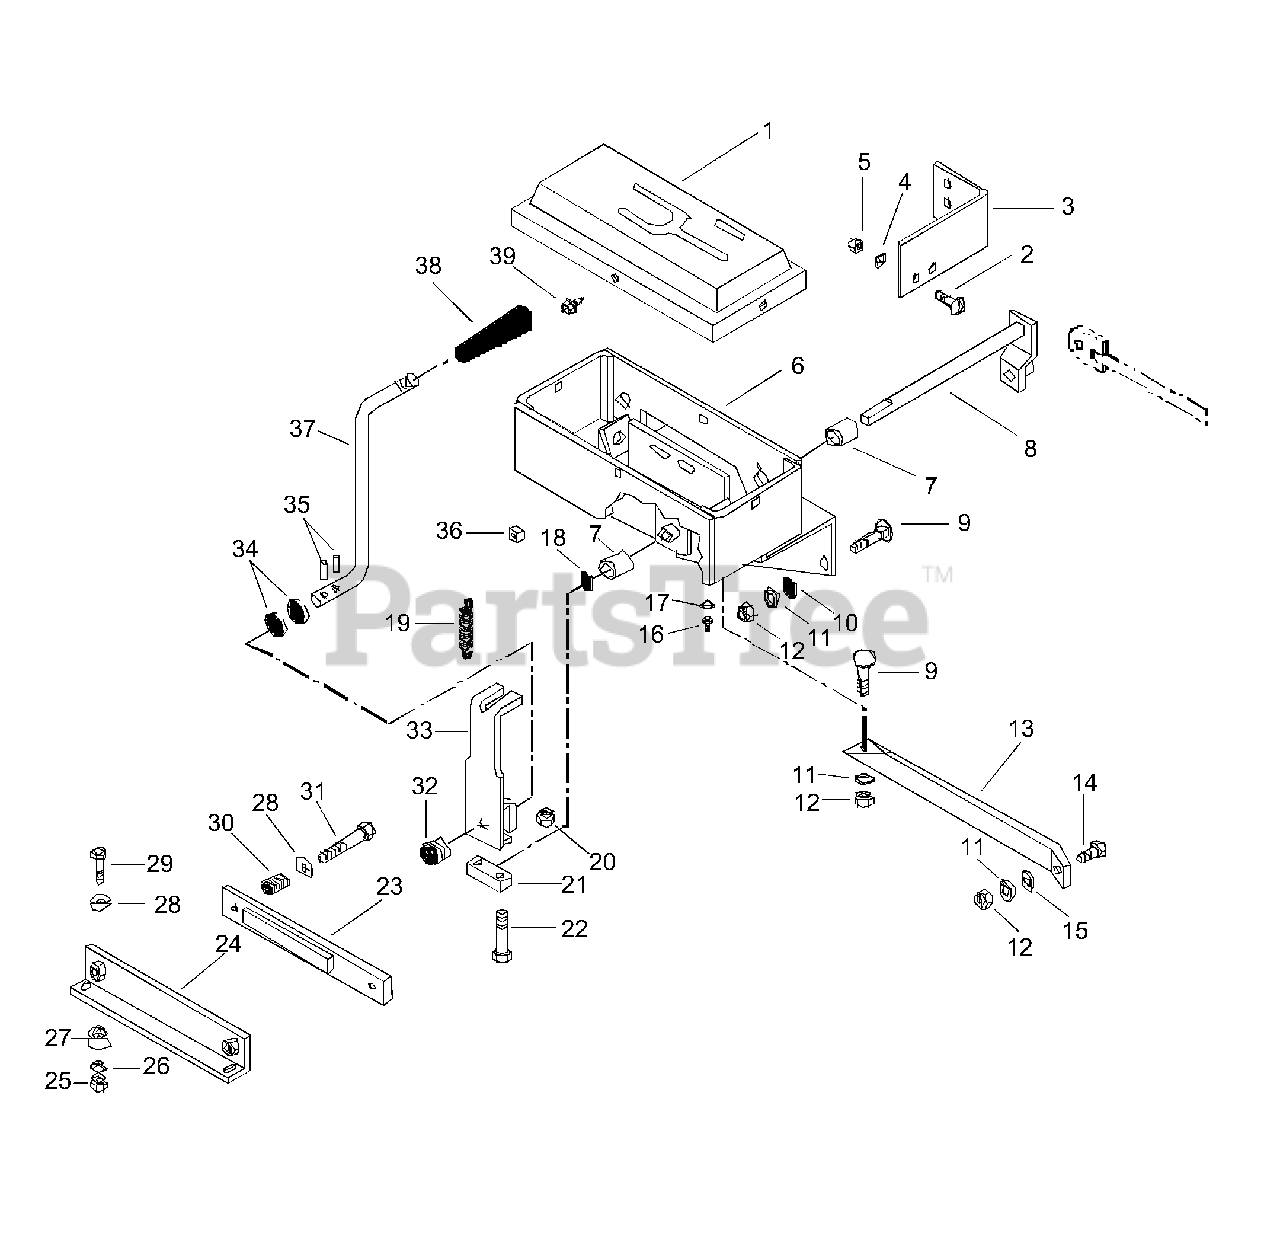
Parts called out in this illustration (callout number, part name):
1	Control Console w/Decal
2	Screw-Machine 10-24 x .50
3	Bracket-Switch
4	Washer-Lock 10 x .047
5	Nut-Hex 10-24
6	Control Box
7	Bushing-Sleeve .625 x .750 x 1.000
8	Shift Shaft
9	Bolt-Round Head Square Neck .38-16 x 1.0
10	Washer-Flat-Steel .438 x 1.0 x .083
11	Washer-Lock .375 x .094
12	Nut-Hex .375-16 Grade 2
13	Brace
14	Bolt-Hex .38-16 x .75 Grade 5
15	Washer-Flat-Steel .406 x .812 x .065
16	Fitting-Lube .25-28 x .256
17	Washer-Lock .250 x .047
18	Washer-Flat-Steel .630 x 1.005 x .062
19	Spring-Tension .072 x .565 x 1.87
20	Nut-Locking-Center .31-18
21	Strap
22	Bolt-Hex .31-18 x 1.50 Grade 5
23	Left Hand Friction Brake
24	Right Hand Friction Brake
25	Nut-Hex .312-18 Grade 2
26	Washer-Lock .312 x .097
27	Spacer .344 x .750 x .625 x .125
28	Washer-Flat-Steel .38 x .875 x .083
29	Bolt-Hex .31-18 x 1.25 Grade 5
30	Spring-Compression .093 x .59 x 1.50
31	Screw-Machine .31-18 x 2.75
32	Grommet .125 x .438
33	Lever
34	Washer-Flat-Steel .520 x .827 x .062
35	Pin-Roll .188 x .88
36	Plastic Grommet
37	Shift Rod
38	Knob
39	Screw-Tapping 10-12 x .50
